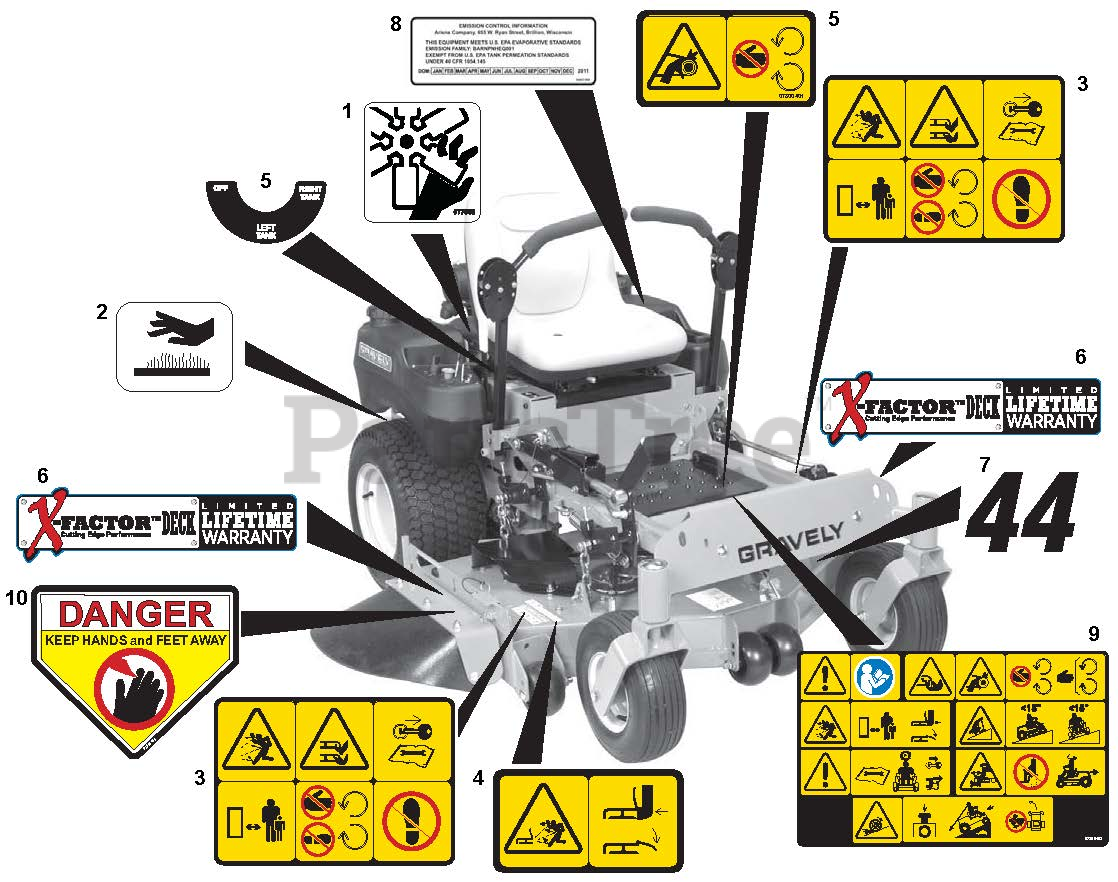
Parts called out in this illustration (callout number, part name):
1	Decal, Danger Fan
2	Decal, Hot Surface
3	Decal, Safety Mower Deck
4	Decal, Safety Deck Guarding
5	Decal, Safety Guarding
6	Decal, X-Factor Deck
7	Decal, 44
8	Decal, EPA Fuel
9	Decal, Main Safety Commercial
10	Decal, Danger
